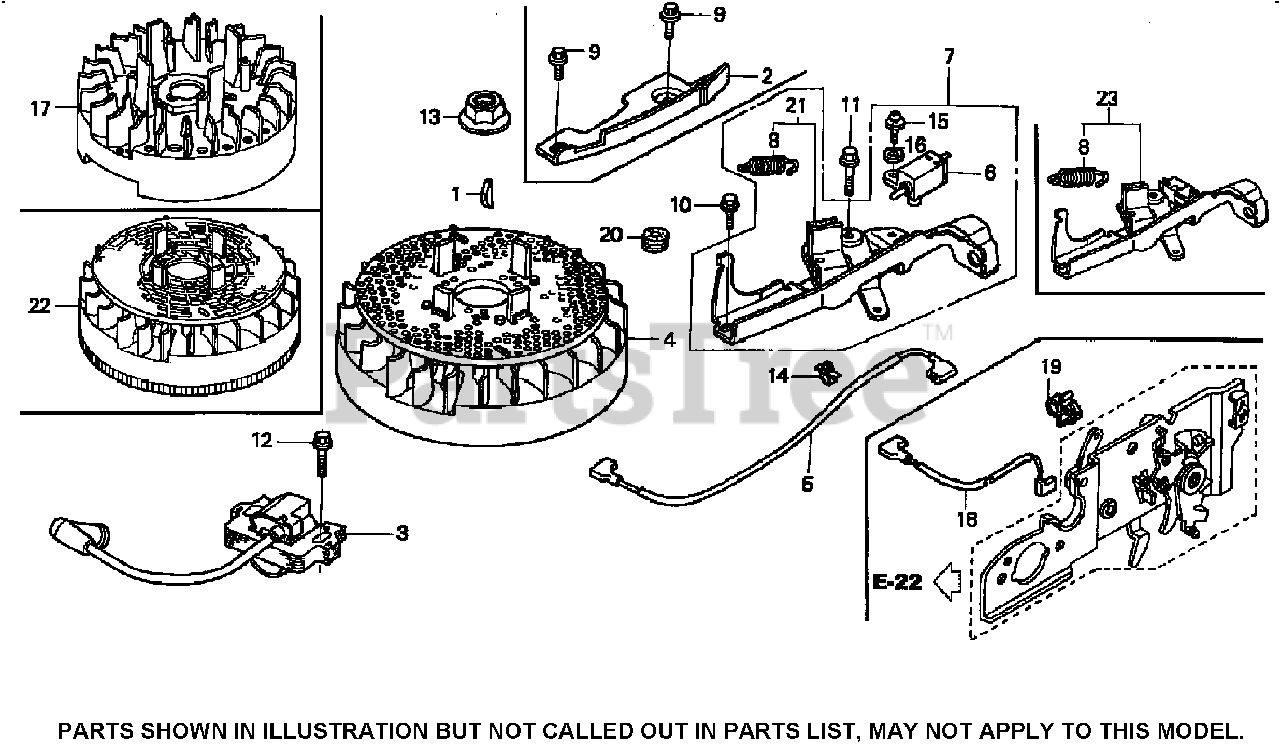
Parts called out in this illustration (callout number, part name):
1	KEY-SPECIAL WOODRUFF (25X18)
3	COIL ASM., IGNITION
4	FLYWHEEL ASM
5	WIRE-STOP SWITCH
6	ENGINE STOP SWITCH ASM
8	SPRING, BRAKE LEVER
10	BOLT-FLANGE (6X14)
11	BOLT-FLANGE
12	BOLT-FLANGE (6X20)
13	NUT-SPECIAL (14MM)
14	CLIP, CABLE (A)
15	SCREW-WASHER
16	WASHER-PLAIN
20	GROMMET A-RR COVER
21	BRAKE SUB ASM
